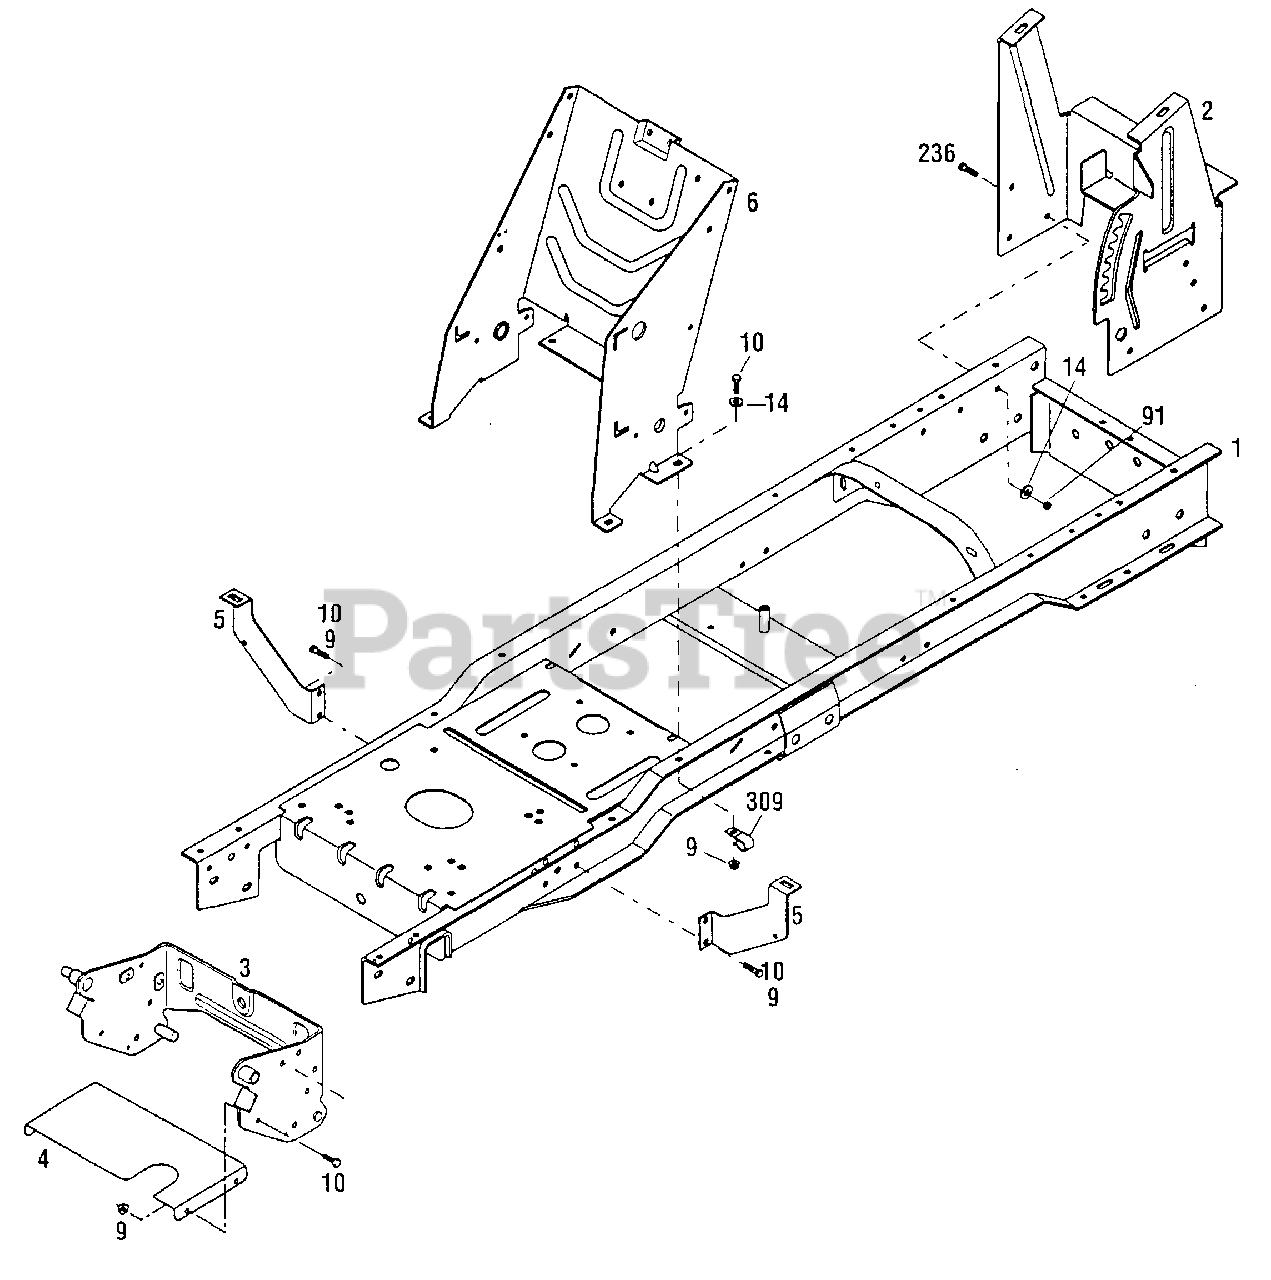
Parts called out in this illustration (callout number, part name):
2	Rear Tank Support
3	Attachment Bracket Assembly
4	Heat Shield
5	Fender Support
6	Console Support
9	Flange Nut, 5/16-18
10	Hex Head Capscrew, 5/16-18 x 3/4
14	Flat Washer, 5/16
91	Locknut, 5/16-18
236	Flange Screw, 5/16-18 x 3/4
309	J-Clamp
